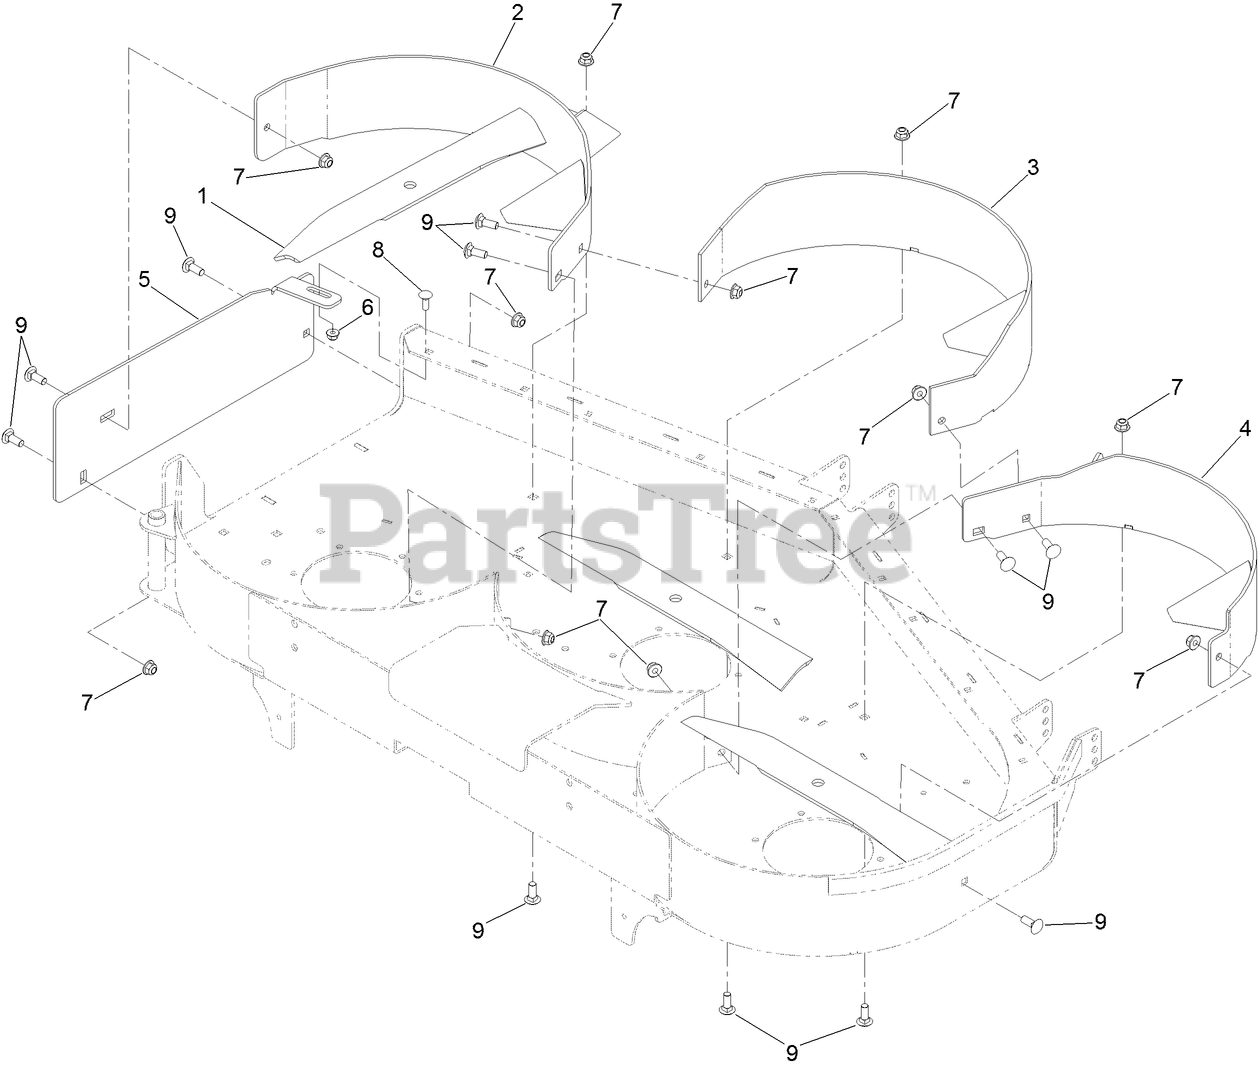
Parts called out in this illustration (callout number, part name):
1	BLADE-ROTARY, RECYCLING 18.0IN
2	BAFFLE-RH
3	BAFFLE-CENTER
4	BAFFLE-LH
5	PLATE-COVER, DISCHARGE
6	NUT-HF, NI
7	NUT-HF, NI
8	SCREW-CARR
9	BOLT-CARR
